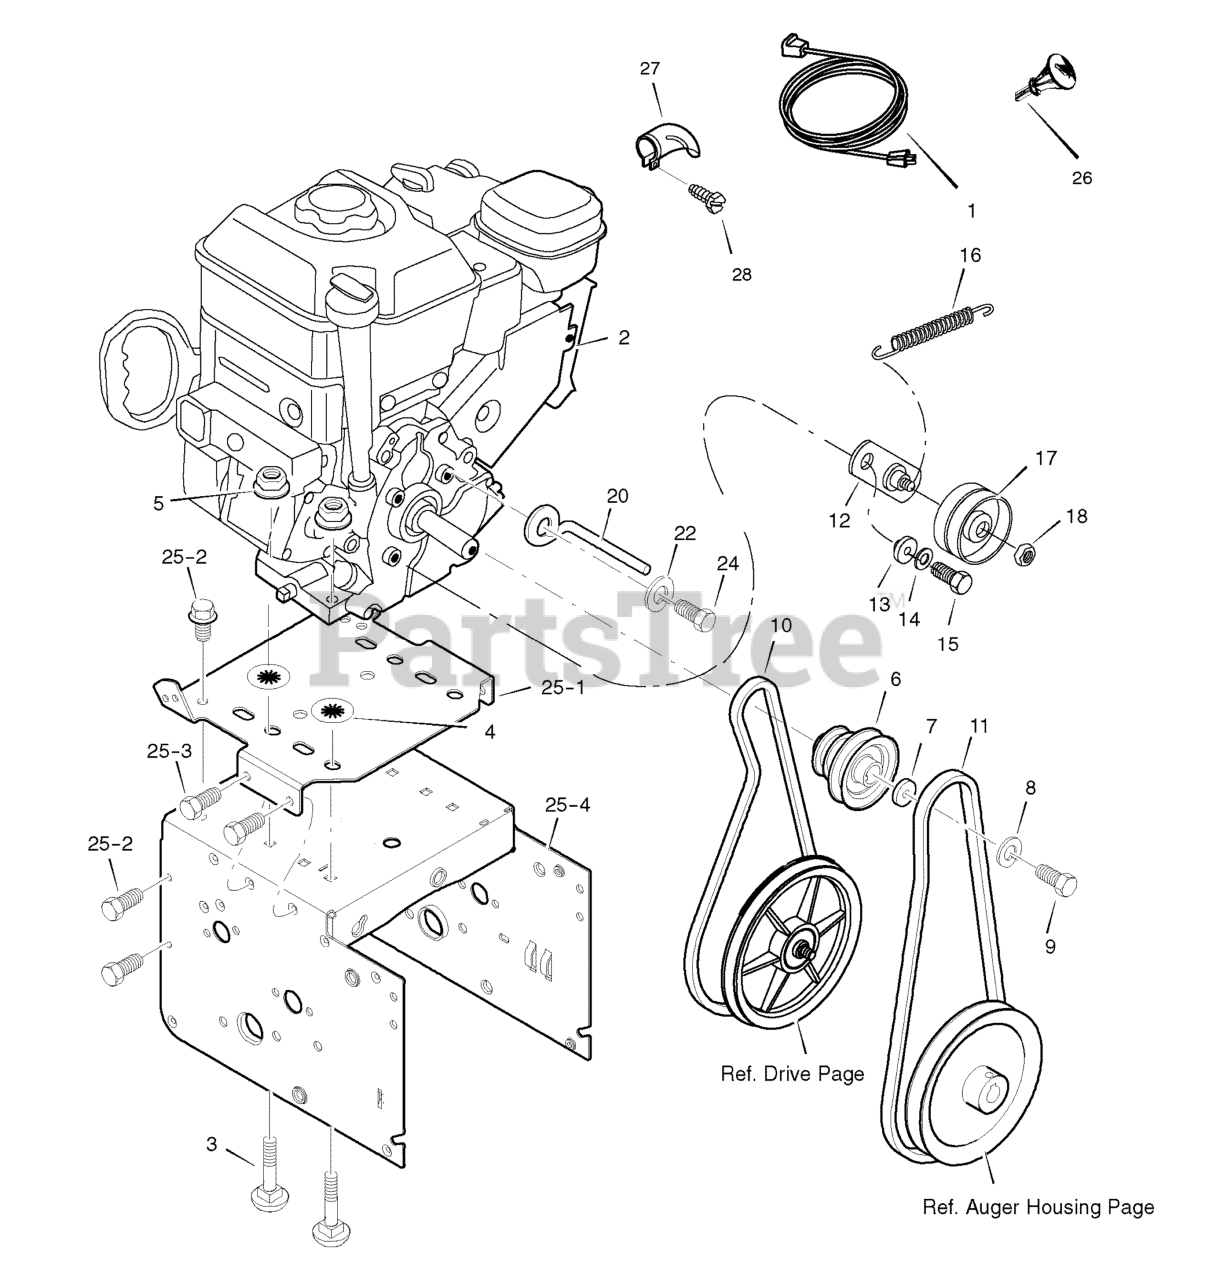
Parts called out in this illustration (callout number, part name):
1	CORD, Electric, 10FT. 110V
2	ENGINE
3	BOLT, CARRIAGE 5/16-18
4	RETAINER, PUSH
5	NUT 5/16-18
6	PULLEY, ENGINE
8	WASHER
9	SCREW, 5/16-24 X 1.00
10	V-BELT, 3L, 33.13
11	V-BELT, 4L, 38.35
12	BRACKET ASSEMBLY, IDLER
13	BUSHING, IDLER BRACKET
14	WASHER
15	SCREW 5/16-24 X 0.75
17	PULLEY, IDLER
18	NUT, JAM 3/8-16
20	GUIDE, ROD BELT
22	WASHER, SPTLK .31 X .58 X .08
24	SCREW, 5/16-24 x 0.75
25	FRAME ASSEMBLY
25-1	PLATE, ENGINE MOUNT
25-2	SCREW 1/4-20 X .63
25-3	SCREW 5/16-18 X .50
25-4	FRAME, MOTOR BOX
26	KEY, IGNITION
27	DEFLECTOR, Muffler
29	OWNER'S MANUAL
